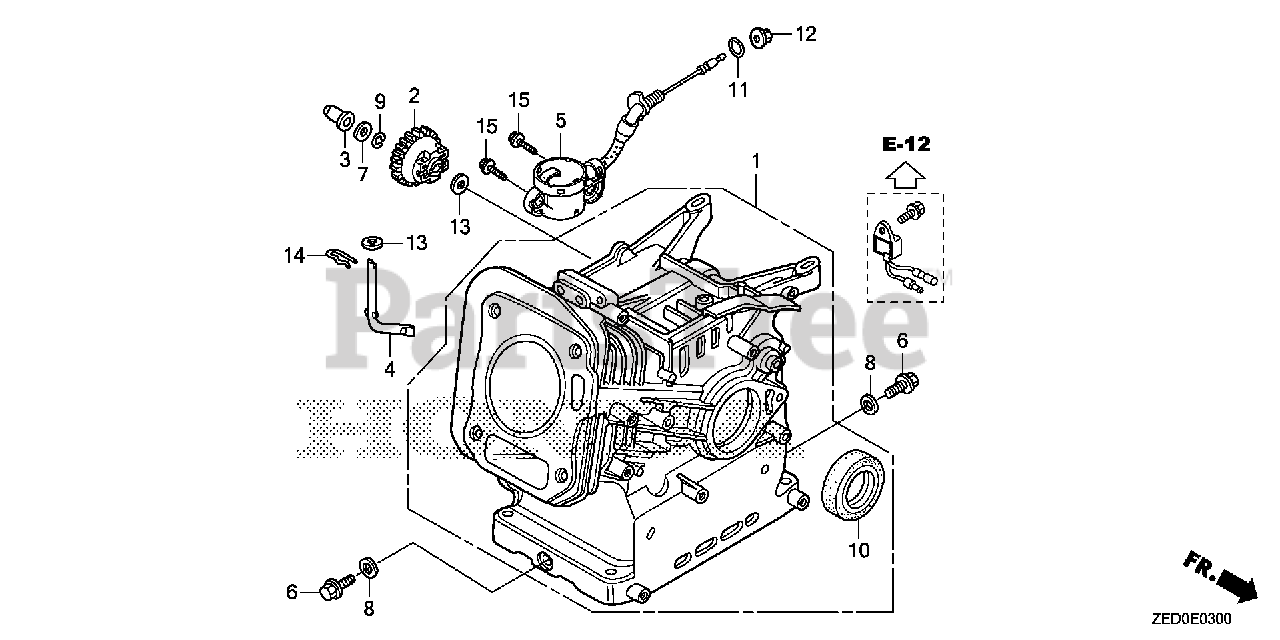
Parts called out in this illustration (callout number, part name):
1	CYLINDER ASSY. (OIL ALERT)
2	GOVERNOR ASSY.
3	SLIDER, GOVERNOR
4	SHAFT, GOVERNOR ARM
5	SWITCH ASSY., OIL LEVEL
6	BOLT, DRAIN PLUG
7	WASHER, THRUST (6MM)
8	WASHER, DRAIN PLUG (10.2MM)
9	CLIP, GOVERNOR HOLDER
10	OIL SEAL (25X41X6)
10	OIL SEAL (25X41X6) (ARAI) (NOT AVAILABLE)
11	O-RING (14MM)
11	O-RING (14MM) (ARAI) Use up to Engine SN 2949254.
11	O-RING (14MM) (NOK)
12	NUT, FLANGE (10MM)
13	WASHER, PLAIN (6MM)
14	PIN, LOCK (8MM)
15	BOLT, FLANGE (6X12) Use up to Engine SN 1543277.
